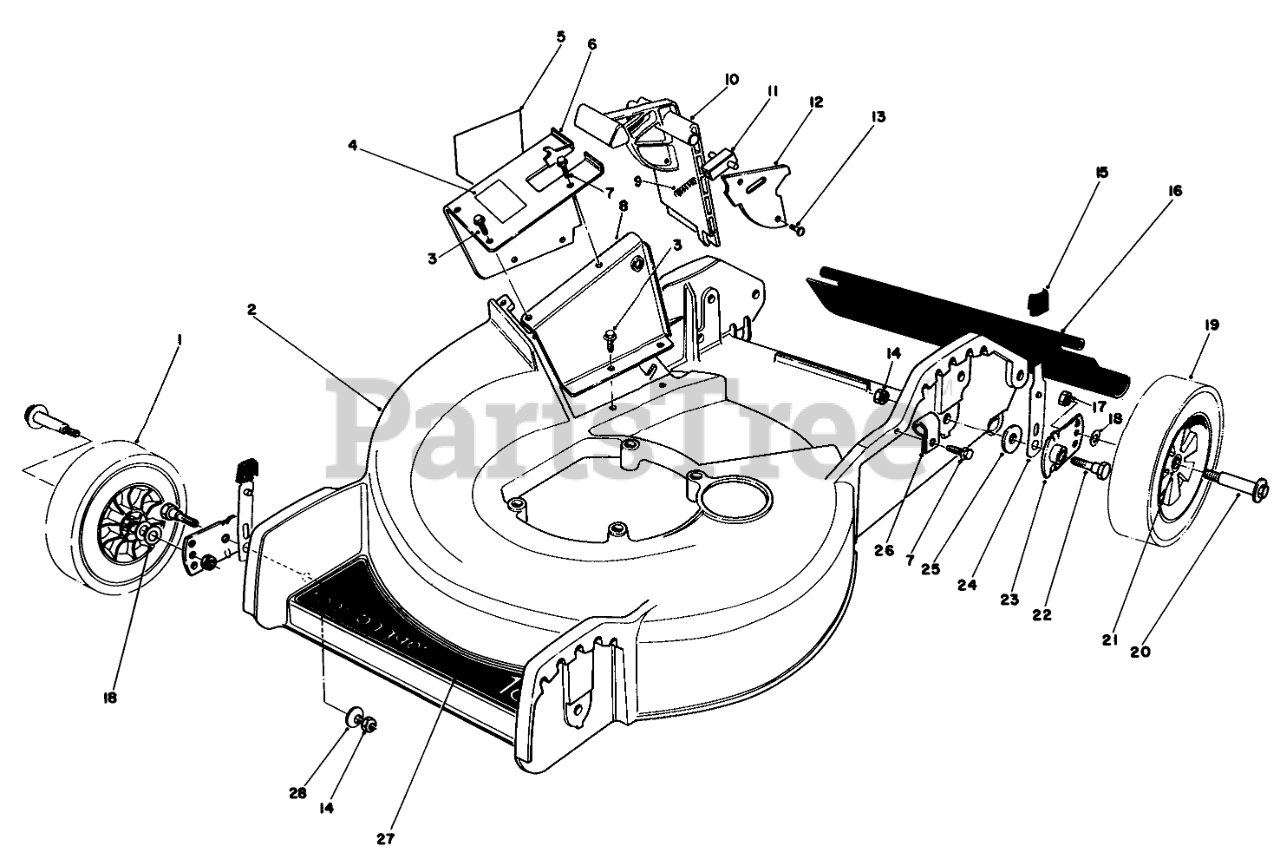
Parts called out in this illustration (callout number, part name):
1	Wheel & Tire Assembly (Incl. Ref. #21)
2	Housing
3	SCREW
4	Decal-Door
5	DECAL-DANGER
6	Tunnel-Outer (Incl. Ref. #4 & 5)
7	SCREW
8	Tunnel-Inner
9	SPRING-COMPRESSION, LATCH
10	Door Mulching
11	Door Latch
12	Cover Door
14	NUT-LOCK, NI
15	KNOB-ARM
16	SHIELD - TRAILING
17	Nut
18	WASHER
19	Wheel & Tire Assembly (Incl. Ref. #21)
20	BOLT-WHEEL
21	BUSHING
22	5/16-18 PIVOT SCREW
23	PIVOT ARM ASSY
24	SPRING ARM ASM
25	PIVOT WASHER
26	CLAMP-NYLON
27	DECAL-DECK
28	WASHER-BELLEVILLE
